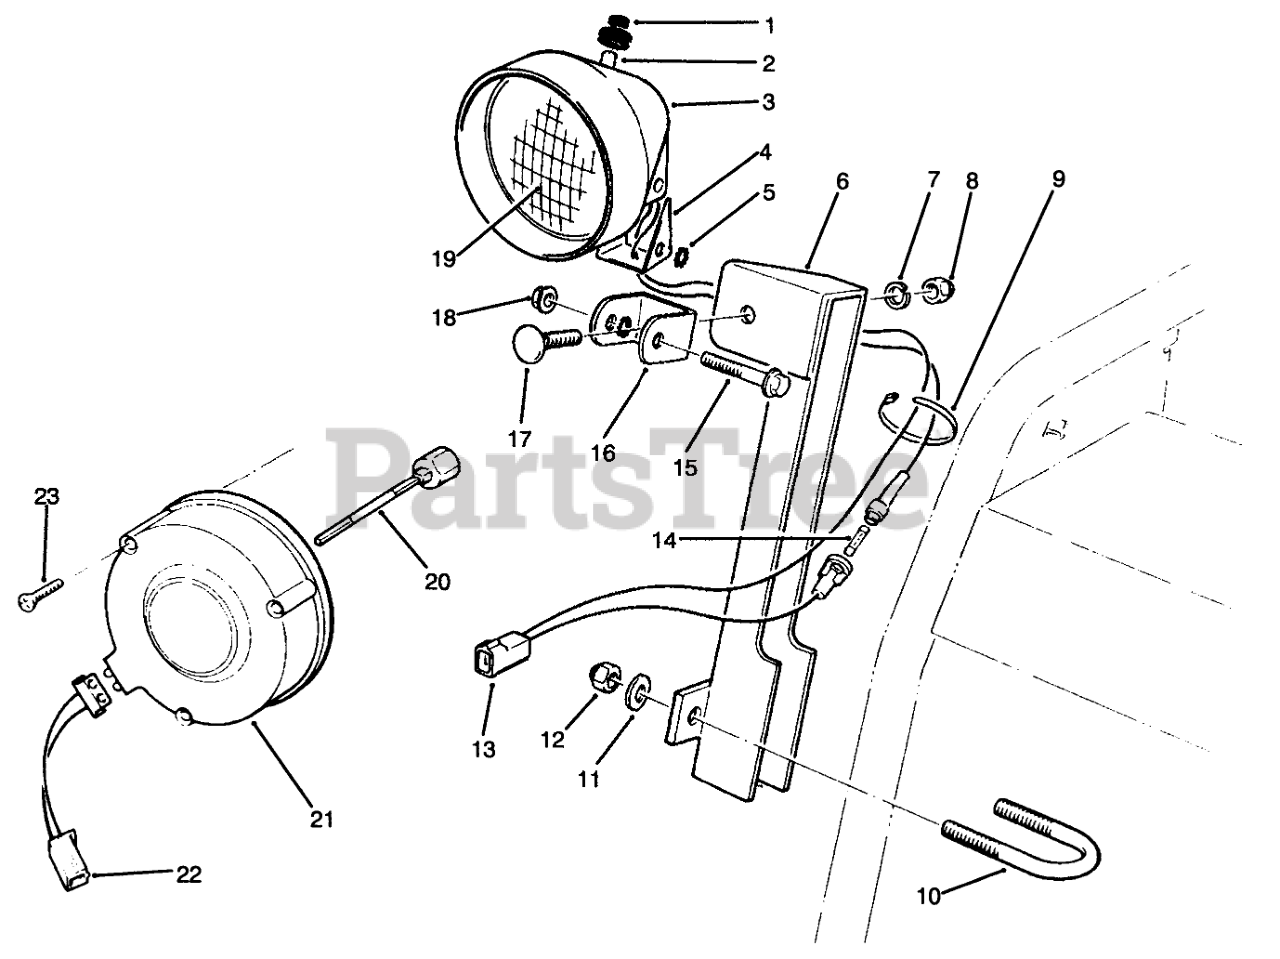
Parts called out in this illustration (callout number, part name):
1	BOOT-SWITCH
2	SWITCH ASM
3	Bucket-Headlamp
4	TO BE DISCONTINED-NOT NEEDED ON PRODUCT
5	WASHER-LOCK
6	Mount-Lamp
7	WASHER-LOCK
8	NUT-HEX
9	TIE-CABLE
10	U-BOLT
11	WASHER-PLAIN
12	NUT-LOCK, NI
13	Wire Assembly
14	Fuse-7-1/2 Amp.
15	SCREW-HH
16	BRACKET
17	BOLT-CARR
18	NUT-HF
19	BEAM-SEALED
20	Shaft-Alternator, 3 Inch
21	Alternator
22	Connector-Wire
23	SELF TAP SCREW
